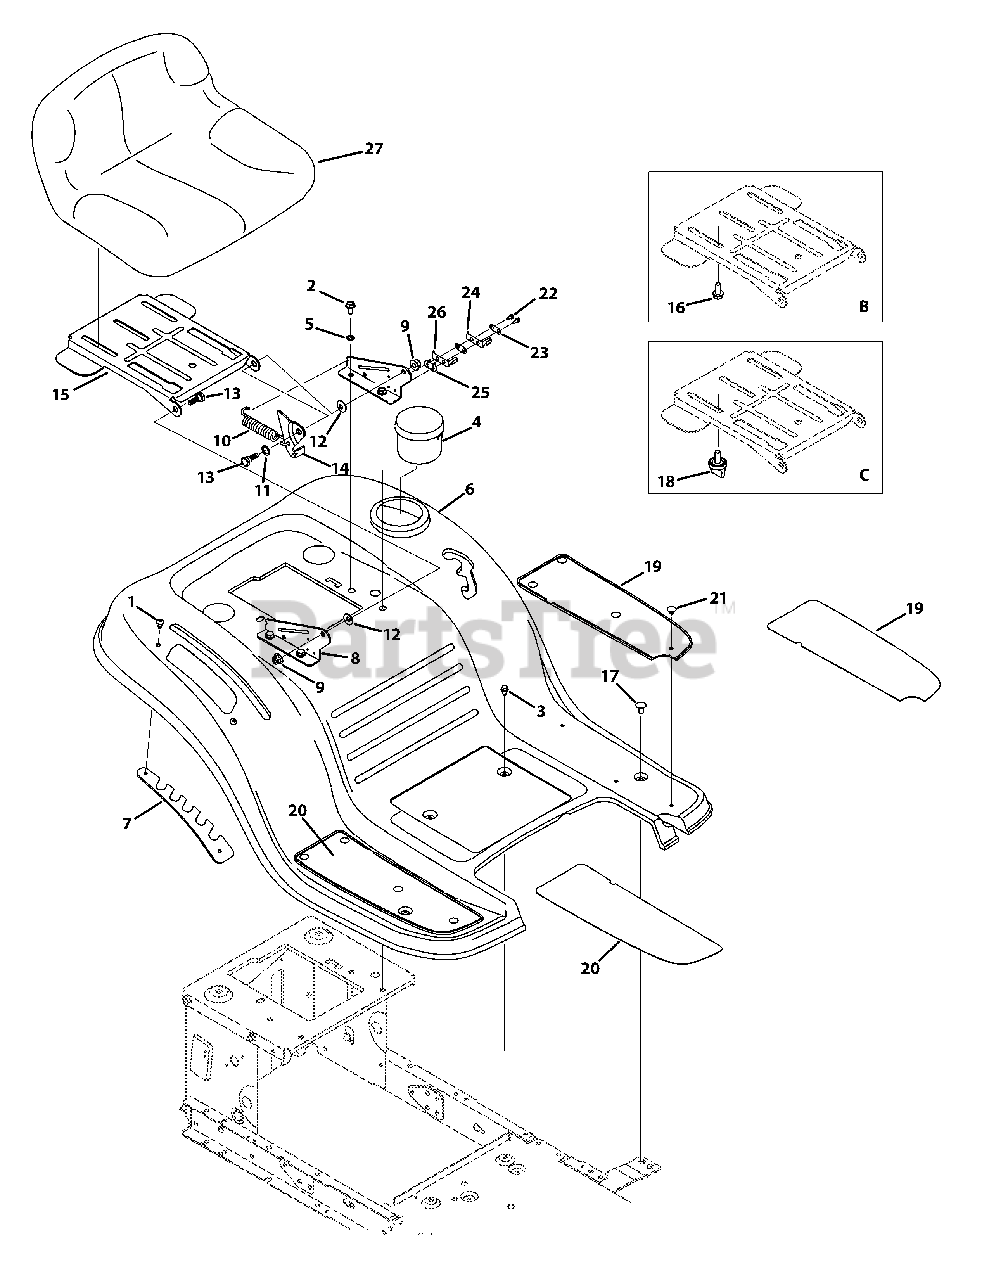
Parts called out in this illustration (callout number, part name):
1	Screw, 1/4-20 x .500
2	Screw, 5/16-18 x .750
3	Screw Pan Torx Head, 1/4-20 x .500
4	Cup Holder
5	Lock Washer, 5/16
6	Fender - Green
6	Fender - Red
6	Fender - Black
7	Lift Adjuster Bracket - Powder Black
8	Seat Mount Bracket - Powder Black
9	Flangelock Nut, 5/16-18
10	Extension Spring
11	Flat Washer, .510x .750 x .033
12	Bell Washer, .340 x .872 x .060
13	Shoulder Screw, 5/16-18 x .437 x .268
14	Lift Seat Bracket
15	Pivot Seat Manual Adjust Bracket
16	Hex Head Flange, 3/8-16 x .875
17	Screw Carriage, 1/4-20 x .62
18	Knob, 3/8-16 x .875
19	Foot Pad, LH
19	Foot Pad, Abrasive, LH
20	Foot Pad, RH
20	Foot Pad, Abrasive, RH
21	Ratchet Clip, .250 x .500
22	Screw, 8-18 x .500
23	Insulator Plate
24	Outer Seat Spring
25	Insulator Boss Plate
26	Inner Seat Spring
27	Medium Back Seat, Black, Set-up B
27	Low Back Seat, Black, Set-up B or C
